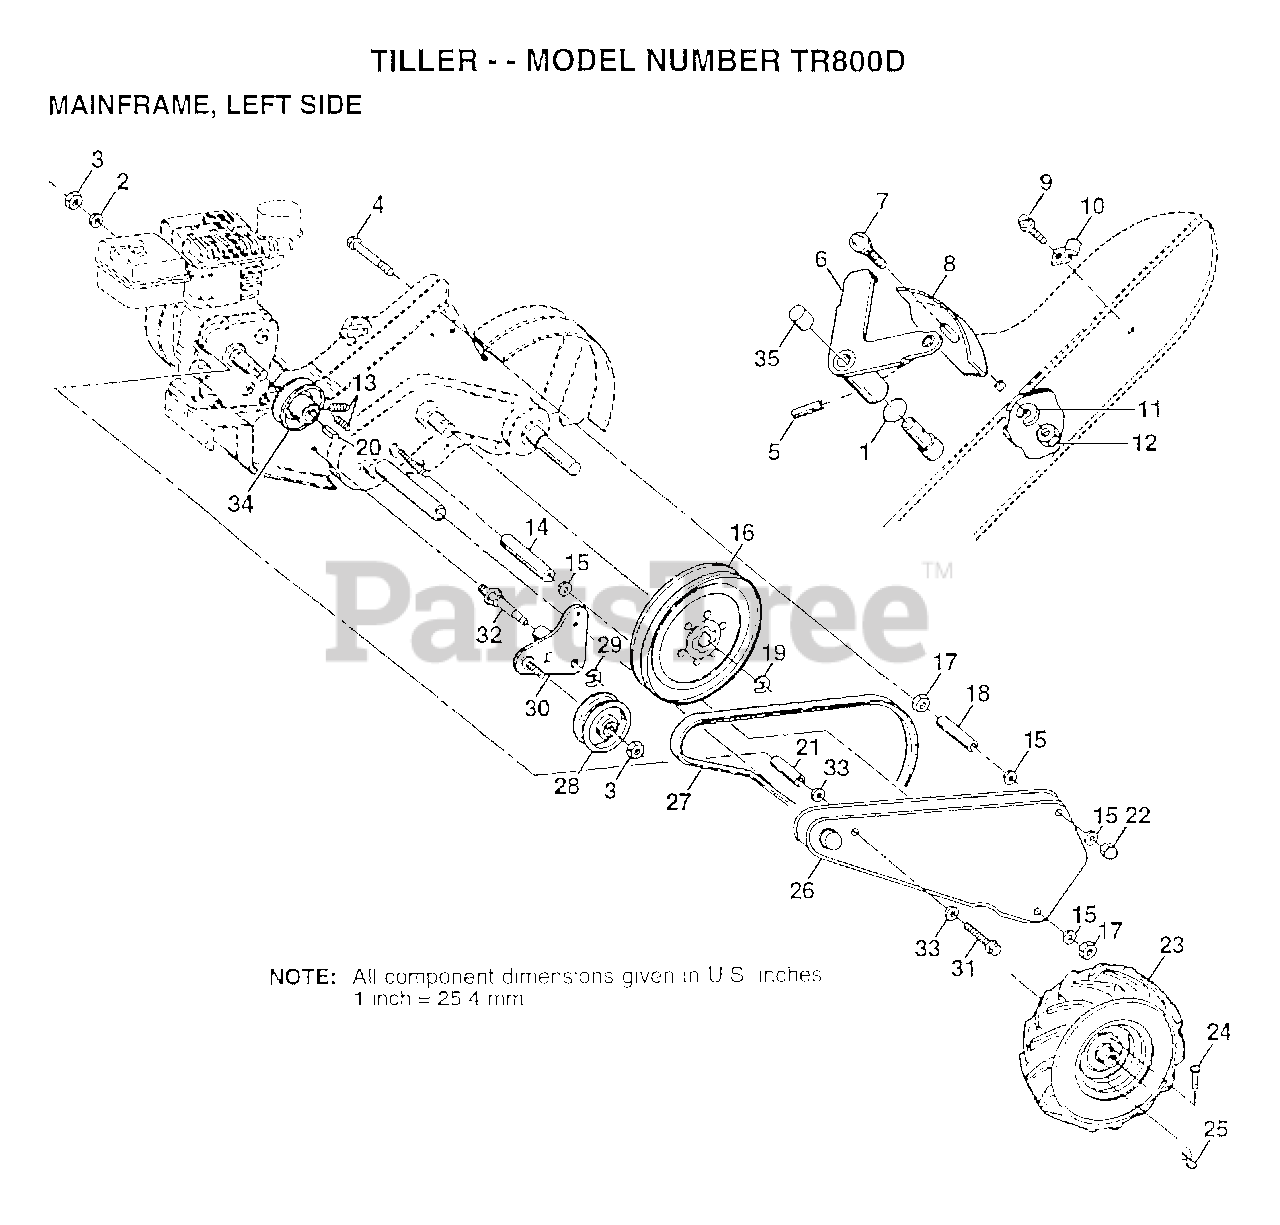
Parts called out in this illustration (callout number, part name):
1	O-RING TI
2	LOCKWASHER
3	NUT.HEX.3/8-16UNC
4	BOLT TI
6	LEVER ASM CRT
7	BOLT
8	PANEL TI
10	CONDIUT CLIP T
11	LOCKWASHER
13	SET SCREW
14	SPACER TI
15	WASHER
16	SHEAVE.TRANS.
17	NUT.HEX.5/16-18
18	SPACER TI
20	KEY TI
21	SPACER.SPLIT
22	NUT TI
23	TIRE TI
24	RIVET.PAN HD.1.75
25	SPRING.RETAINER
26	GUARD.PNT.BELT.
27	BELT.DRIVE
29	KLIP RING
31	BOLT1/2-20UNF2.75
32	SHAFT.IDLER
34	SHEAVE CRT
35	CAP PLUNGER BLACK
